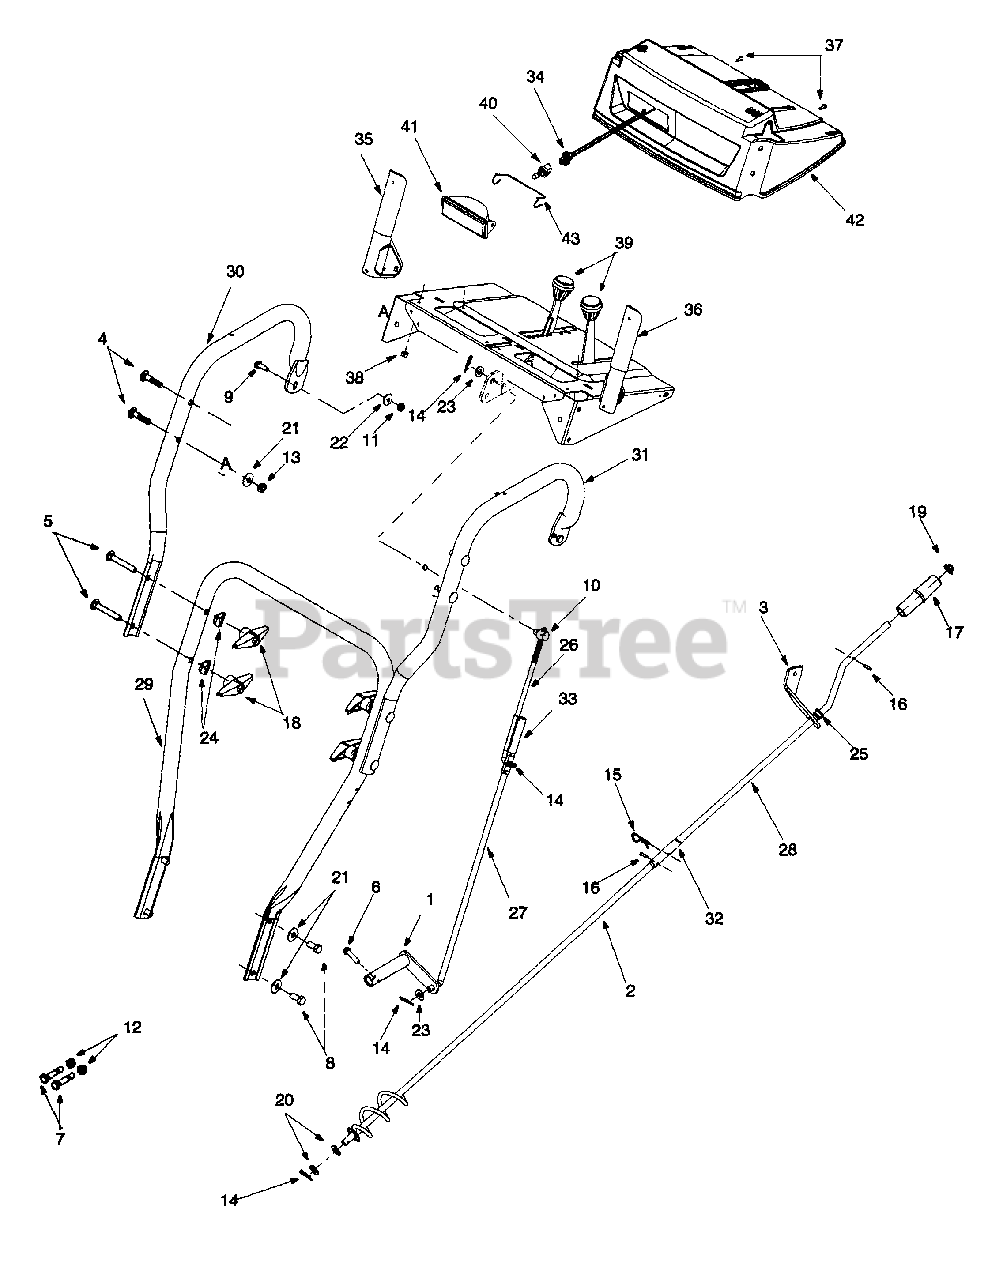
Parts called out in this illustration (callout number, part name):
4	Carr. Bolt 5/16-18 x 1.5
5	Carr. Screw 5/16-18 x 2.25 Gr.5
6	Hex Washer Screw 1/4-20 x 1.0
7	Shear Bolt 5/16-18 x 1.5
8	Hex Bolt 5/16-18 x 0.75 Gr.5
9	Hex Bolt 1/4-20 x 0.75 Gr.5
10	Ferrule
11	Hex Nut: 1/4-20
12	Hex Lock Nut
13	Hex Nut: 5/16-18
14	Cotter Pin
15	Click Pin
16	Roll Pin
17	Chute Crank Knob
18	Wing Nut
19	Push Cap
20	Flat Washer
21	Belleville Washer
22	Bell Washer
23	Flat Washer
24	Saddle Washer
25	Plastic Bushing
26	Shift Rod: Upper
27	Shift Rod: Lower
33	Clutch Rod Connector
34	Harness, Halogen Light
35	Handle Engagement Assembly: RH Black
36	Handle Engagement Assembly: LH Black
37	Hex washer Hd. Sp. screw
38	Hex Sems Nut
39	Shift Knob
40	Halogen Lamp
41	Lamp Housing
42	Handle Panel: yellow w/Tilt, Light
43	Halogen Retainer: Handle
